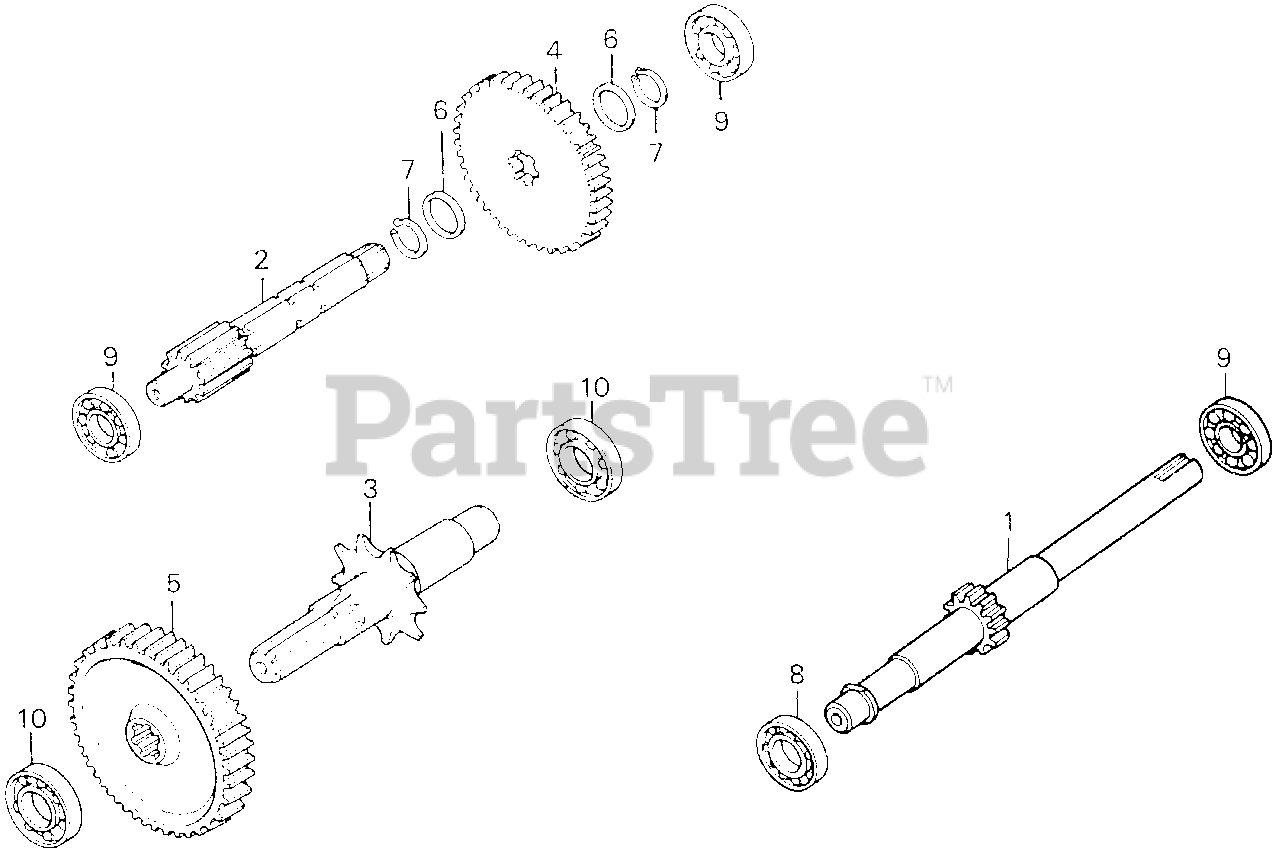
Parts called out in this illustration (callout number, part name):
1	SHAFT, INPUT (NOT AVAILABLE)
2	COUNTERSHAFT
3	SHAFT, FINAL
4	GEAR, COUNTER (NOT AVAILABLE)
5	GEAR, FINAL
6	WASHER, THRUST (17MM)
7	CIRCLIP (OUTER) (17MM)
8	BEARING, RADIAL BALL (6003)
9	BEARING, RADIAL BALL (6202)
10	BEARING, RADIAL BALL (6203)
